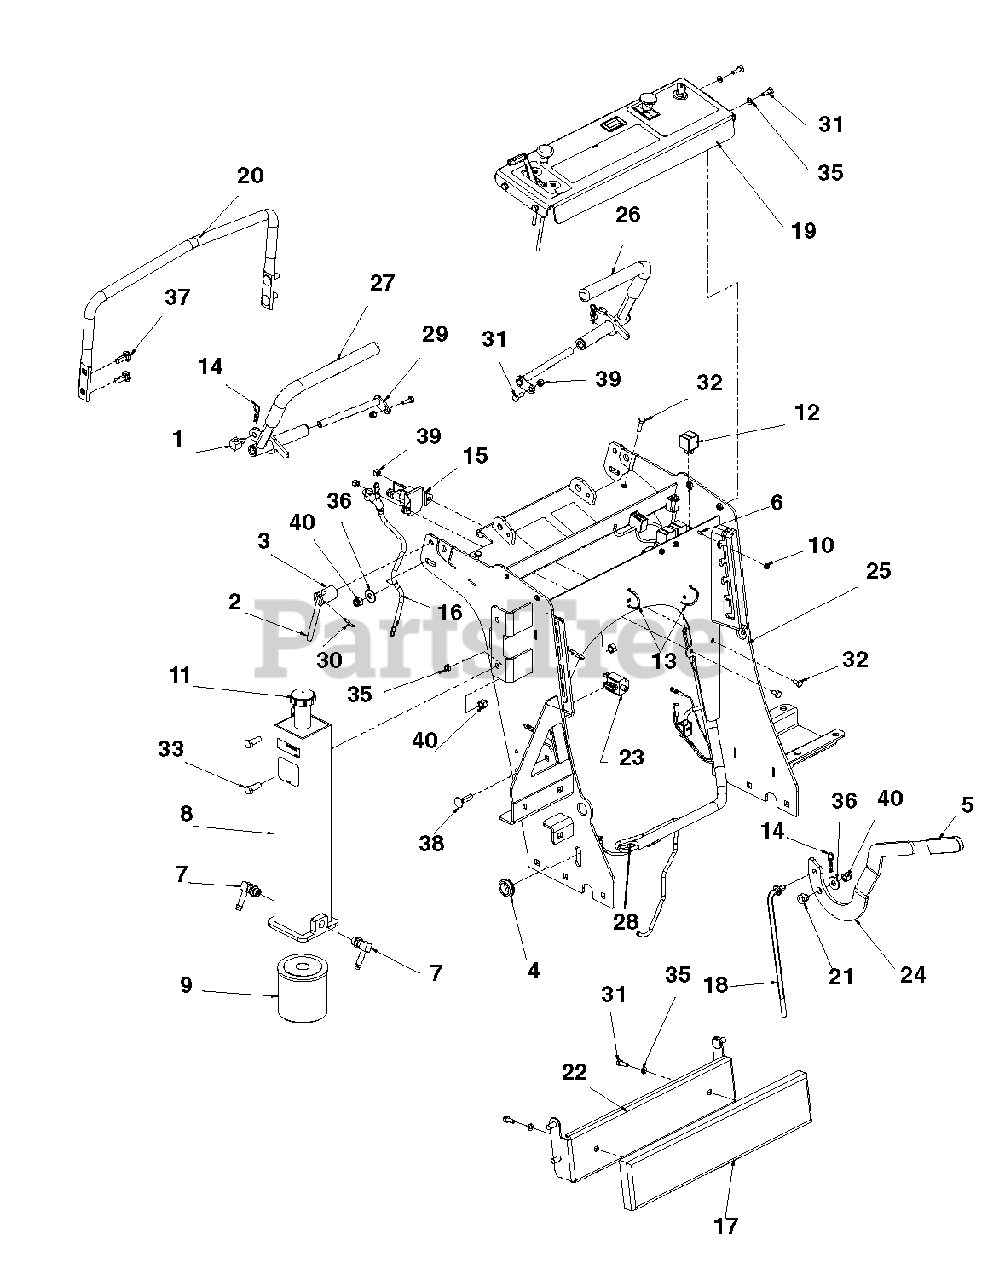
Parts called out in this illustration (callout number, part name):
1	Swivel Adjuster
2	Lever, Lock Y
3	Base, Lock Lever Y
4	Grommet, Rubber .88ID x 1.38OD x .14
5	Grip, PVC .250 x 1.00 x 3.63
6	Screw, 8-32 x .50 Y
7	Fitting, 90 9/16 MOR x 3/8 HOSE
8	Weldment, Reservior Hydraulic
9	Filter, Oil
10	Nut, 8-32 Elastic Stop
11	Cap, Filler Oil
12	Relay, Iso Mini Elec.
13	Cable Tie, .15 x 8.50
14	Pin, Hair .091 x 1.63
15	Solenoid, 12 V Starter
16	Cable, 12" Starter
17	Pad, Thigh
18	Link, Brake
19	Assembly, Control Panel w/Decals (switches sold seperately)
20	Handle, Support
21	Bushing, Brake Pivot Y
22	Weldment, Thigh Pad Bracket
23	Switch, NO-NO-NC Grey Plunger
24	Brake Lever, Offset
25	Weldment, Console 34 w/Decals
26	RH Control Lever w/Grip
27	LH Control Lever w/Grip
28	Harness, Wiring
29	Weldment, Pin and Lock
30	Pin, Spring 5/32 x 1
31	Bolt, Hex .25-20 x .75 Grade 5
32	Bolt, .25-20 x 1.00 Hex 5 Y
33	Bolt, Hex .38-16 x 1.00 Grade 5
34	Nut, .25-20 Standard Hex Grade 5 Y
35	Washer, .250 Med Spring Lock
36	Washer, .375 Reg Flat
37	Bolt, Round Head Square Neck .38-16 x 1.00 G 5
38	Bolt, Round Head Square Neck .38-16 x 1.25 G 5
39	Nut, Locking-Nylon .250-20
40	Nut, Locking-Nylon .38-16
